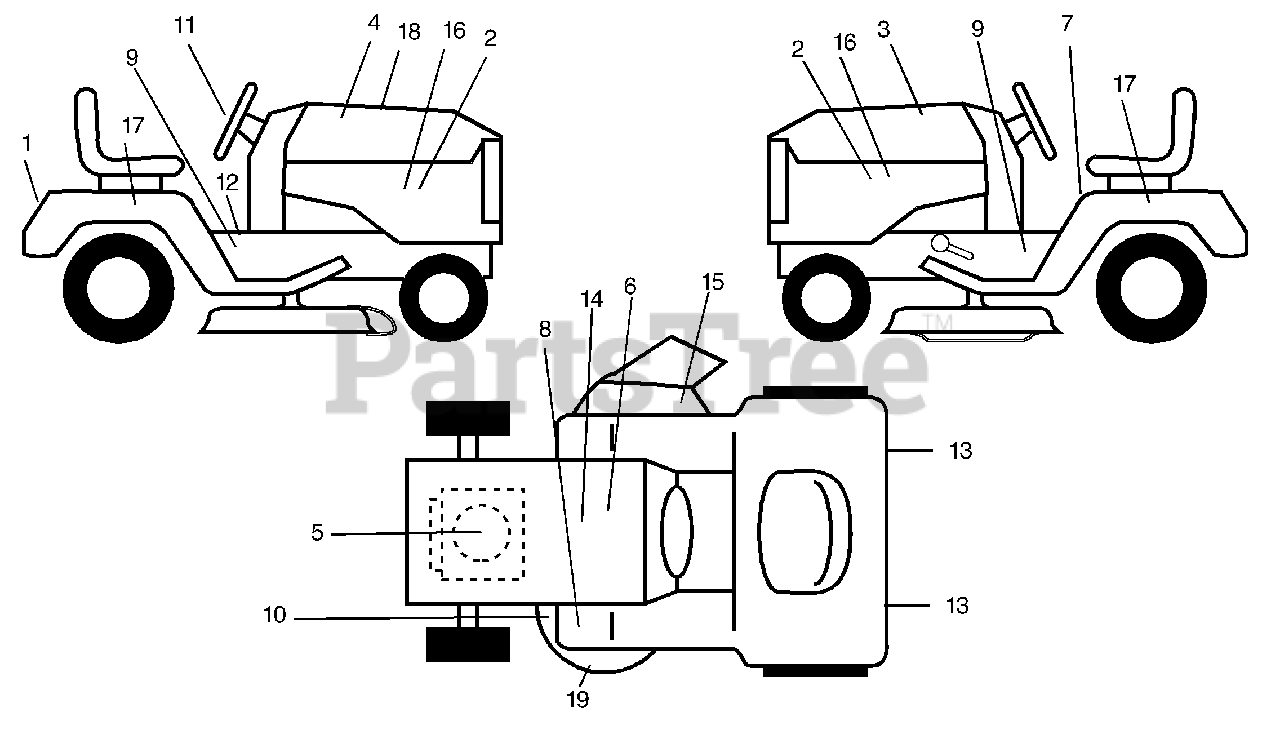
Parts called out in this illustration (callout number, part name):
1	Decal Fender
2	Decal Side Panel
3	Decal Hood LH
4	Decal Hood RH
5	Decal HP Engine
6	Decal Battery
7	Decal Danger Fender English
8	Decal Clutch/brake English
9	Decal Chassis
10	Decal V-Belt Sch
11	Decal Steering
12	Decal Oper s DL Eng/Fr
13	Reflector Taillight
14	Decal, Btry Dngr/Psn
15	Decal, Warning Mower
16	Decal Panel
17	Decal Fender Side
18	Decal Replacement Hood
19	Decal Deck Mulch/Vented
